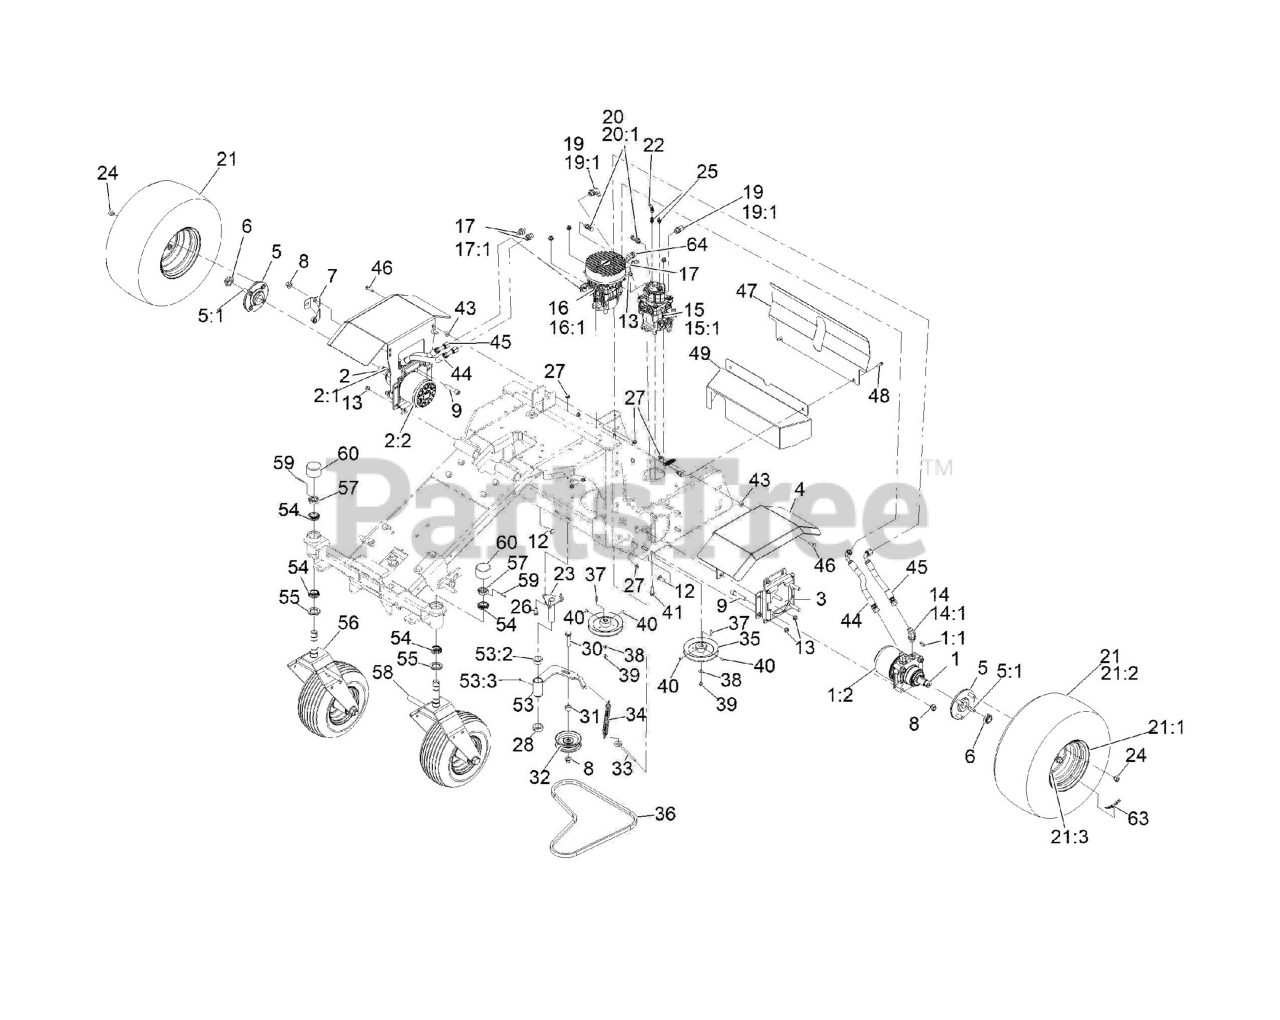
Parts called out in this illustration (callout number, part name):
1	MOTOR-WHEEL, LH
1:1	KEY-WOODRUFF
1:2	SEAL KIT
2	MOTOR-WHEEL, RH
2:1	KEY-WOODRUFF
2:2	SEAL KIT
3	X-REF 142-0270-05
4	FENDER-AE
5	HUB-WHEEL
5:1	STUD-1/2-20 X 1.55
6	LOCKNUT
7	BRACKET-HOPPER, SPEEDOMET
8	Nut-Lock 1/2-13
9	Screw-HSH
12	BOLT-CARR
13	NUT-HF, NI
14	FITTING-ELBOW, 45 DEG
14:1	O-RING
15	PUMP-HYD,LH,W/ AUX,ZPLUG,
15:1	SPRING-EXTENSION
16	PUMP-HYD, RH,W/ FAN ZPLUG
16:1	SPRING-EXTENSION
17	FITTING-STRAIGHT
17:1	O-RING
19	FITTING-ELBOW, 90 DEG
20	FITTING-ELBOW, 90 DEG
20:1	O-RING
21	WHEEL AND TIRE ASM
21:1	Rim-8 X 7, Black
21:3	Stem-Valve
22	4MJIC-4FJIC 90 DEG SWIVEL
23	PIVOT-IDLER
24	NUT-LUG
25	FITTING-STRAIGHT
26	SCREW-HH
27	NUT-HF, NI
30	Screw-HHF
32	PULLEY-IDLER, FLAT
33	5/16-18 X 6 EYE BOLT W/ 5
34	SPRING-EXTENSION
35	PULLEY, DRIVE, 5-5/8" 17M
36	B54 BELT 2011+ ZPLUG (16C
39	SCREW-HHF
40	Setscrew-HSH
41	SCREW-HHF
44	Hose ASM-HYD HP
45	Hose ASM-HYD HP
46	Bolt-Carriage 5/16-18 X 1 1/4
47	GUARD-PUMP
48	SCREW-HHF
53	ARM-IDLER, ASM
53:2	BUSHING-FLANGE
53:3	FITTING-GREASE, ZERK
54	CONE-BEARING, OUTER
55	SEAL-GREASE
56	Caster ASM - RH
57	NUT-SHH
58	Caster ASM - LH
59	Pin-Cotter
60	CAP-DUST, RUBBER
63	DECAL-TORQUE, WHEEL HUB LUG
64	FITTING-ELB 90
